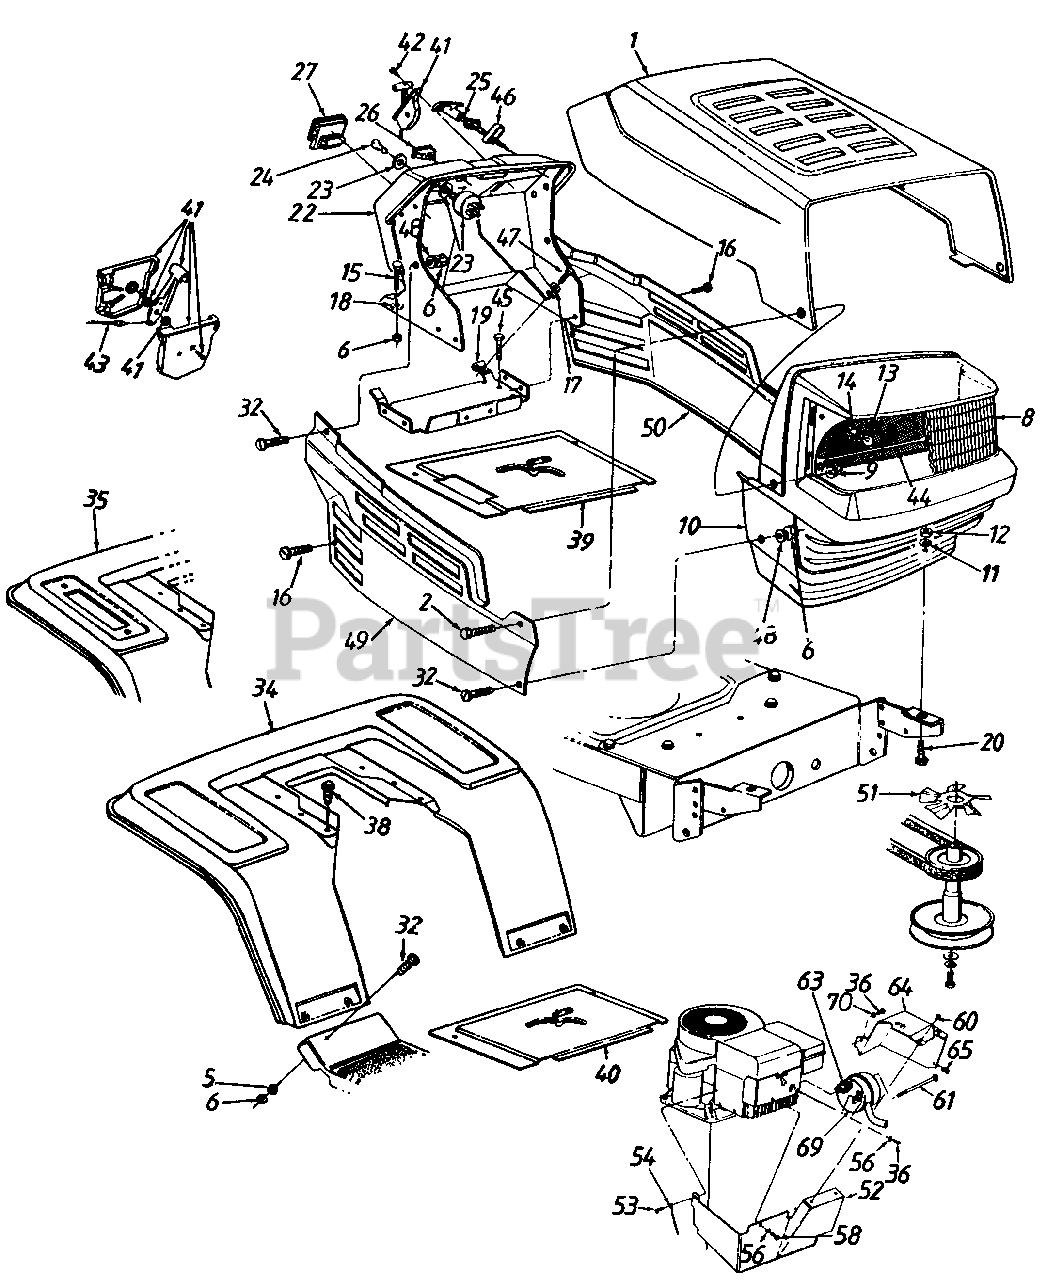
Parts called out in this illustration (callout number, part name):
6	Hex Nut 1/4-20 Thd.
8	Headlight Lens
9	Flange L-Nut 1/4-28 Thd.
10	Grille
11	Fl-Wash .344" I.D. x 1" O.D.
12	Hex Nut 5/16-18 Thd.
13	Lamp
14	Socket
15	Carriage Bolt 1/4-20 x .75" Lg.
16	Hex Wash. Hd. TT-Tap Scr. 1/4-20 x .5" Lg.
17	Fl-Wash .281" I.D. x .73" O.D.
18	Bolt Retainer 1/4" I.D.
19	Speed Nut 1/4-20 Thd.
20	Hex Bolt 5/16-18 x .75" Lg.
23	Ignition Switch
24	Ignition Key
25	Choke Control
26	Light Switch
27	Ammeter
32	Truss Mach. Scr. 1/4-20 x .5" Lg.
38	Hex Wash. Hd. AB-Tap Scr. 5/16 x .75" Lg.
41	Throttle Box Ass'y.
42	Truss Mach. AB-Tap Scr. #10 x .5" Lg.
43	Throttle Control Wire
44	Grille Reflector Label
45	Hex Wash. Hd. 8-Tap Scr. 5/16-18 x .5" Lg.
46	Choke Retainer
47	Hex TT-Tap Scr. 1/4-20 x .75" Lg.
48	Bell-Wash. 1/4" I.D.
52	Muffler Heat Shield - Front
53	Truss Mach. Scr. 5/16-18 x .75" Lg.
54	Ground Wire
56	Spr. Wash. 1/4" I.D.
58	Hex Bolt 1/4-20 x 3/8" Lg.
60	Hex B-Tap Scr. #10 x .38" Lg.
61	Shoulder Bolt
63	Exhaust Gasket
64	Muffler Heat Shield - L.H.
65	Speed Nut #10-24 Thd.
69	Muffler
70	L-Wash. 1/4" I.D.
